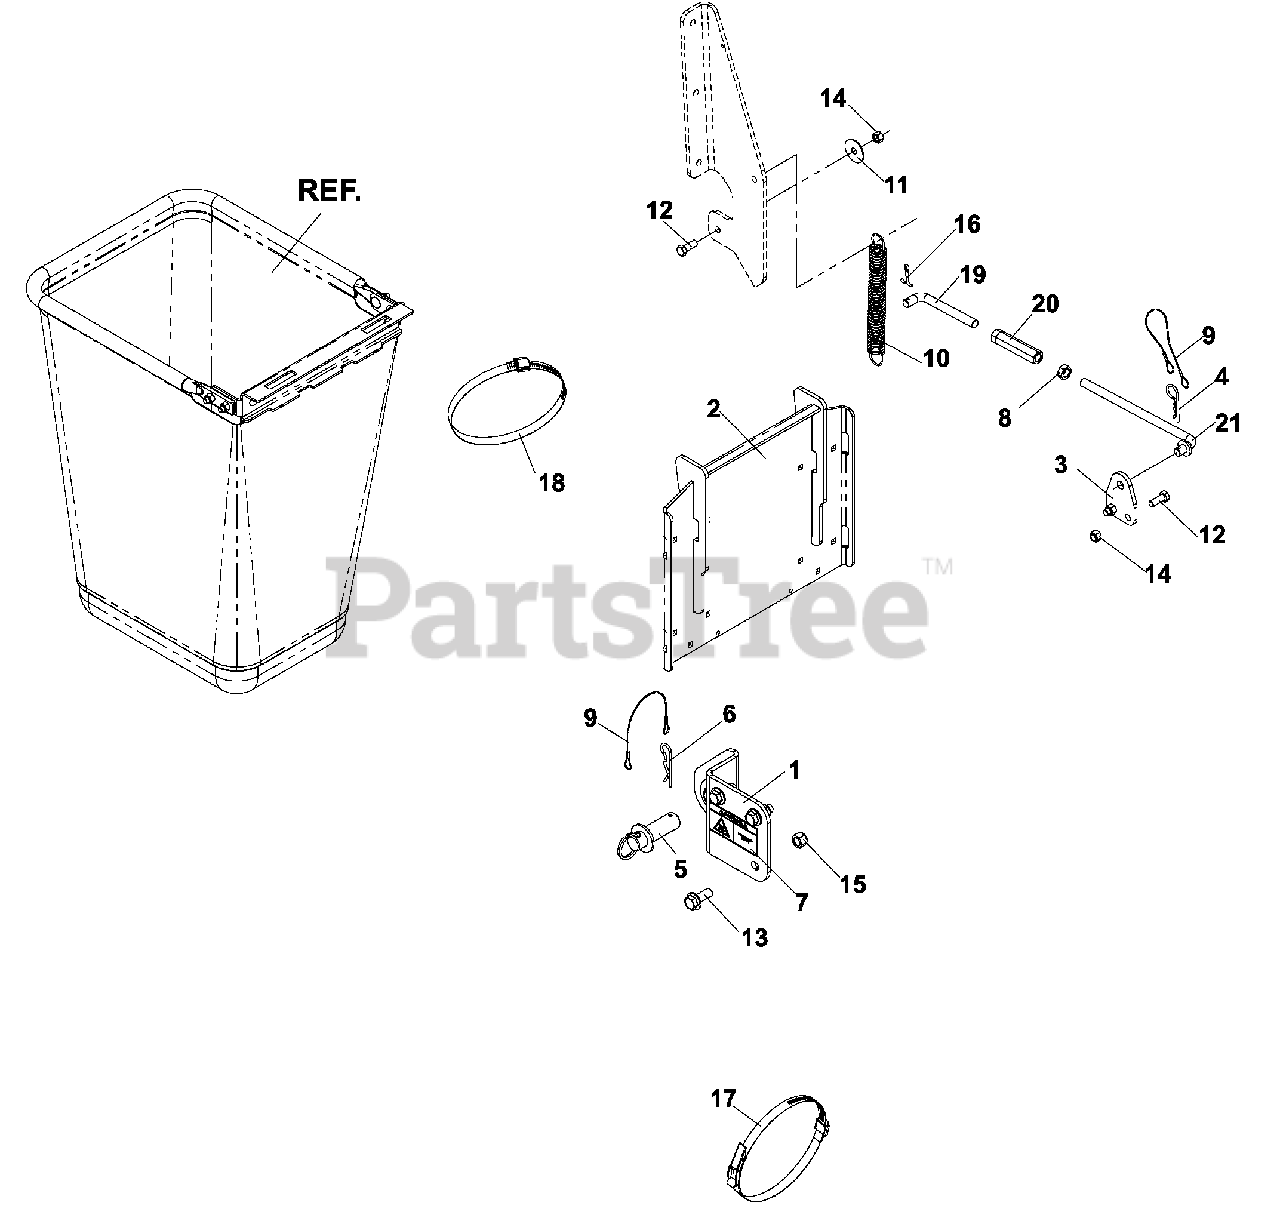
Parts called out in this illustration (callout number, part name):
1	HITCH BRACKET, RIGHT, W/DECAL
2	REAR GUARD
3	SUPPORT BRACKET
4	HAIRPIN #4
7	DECAL, HOT SURFACE
8	NUT, 1/2-20, HEX JAM
11	FRICTION WASHER
12	HCS, 3/8-16 x 1, GR5
13	HFS, 1/2-13 X 1 1/2
14	NUT, 3/8C, NYLOC
15	NUT, 1/2C, NYLOC
16	COTTER PIN, 5/32 X 1 1/4
17	OVER CENTER BAND
18	HOSE CLAMP 6"-& 7"
19	SUPPORT LINKAGE, LH
20	TURNBUCKLE, 1/2"
21	SUPPORT LINKAGE
